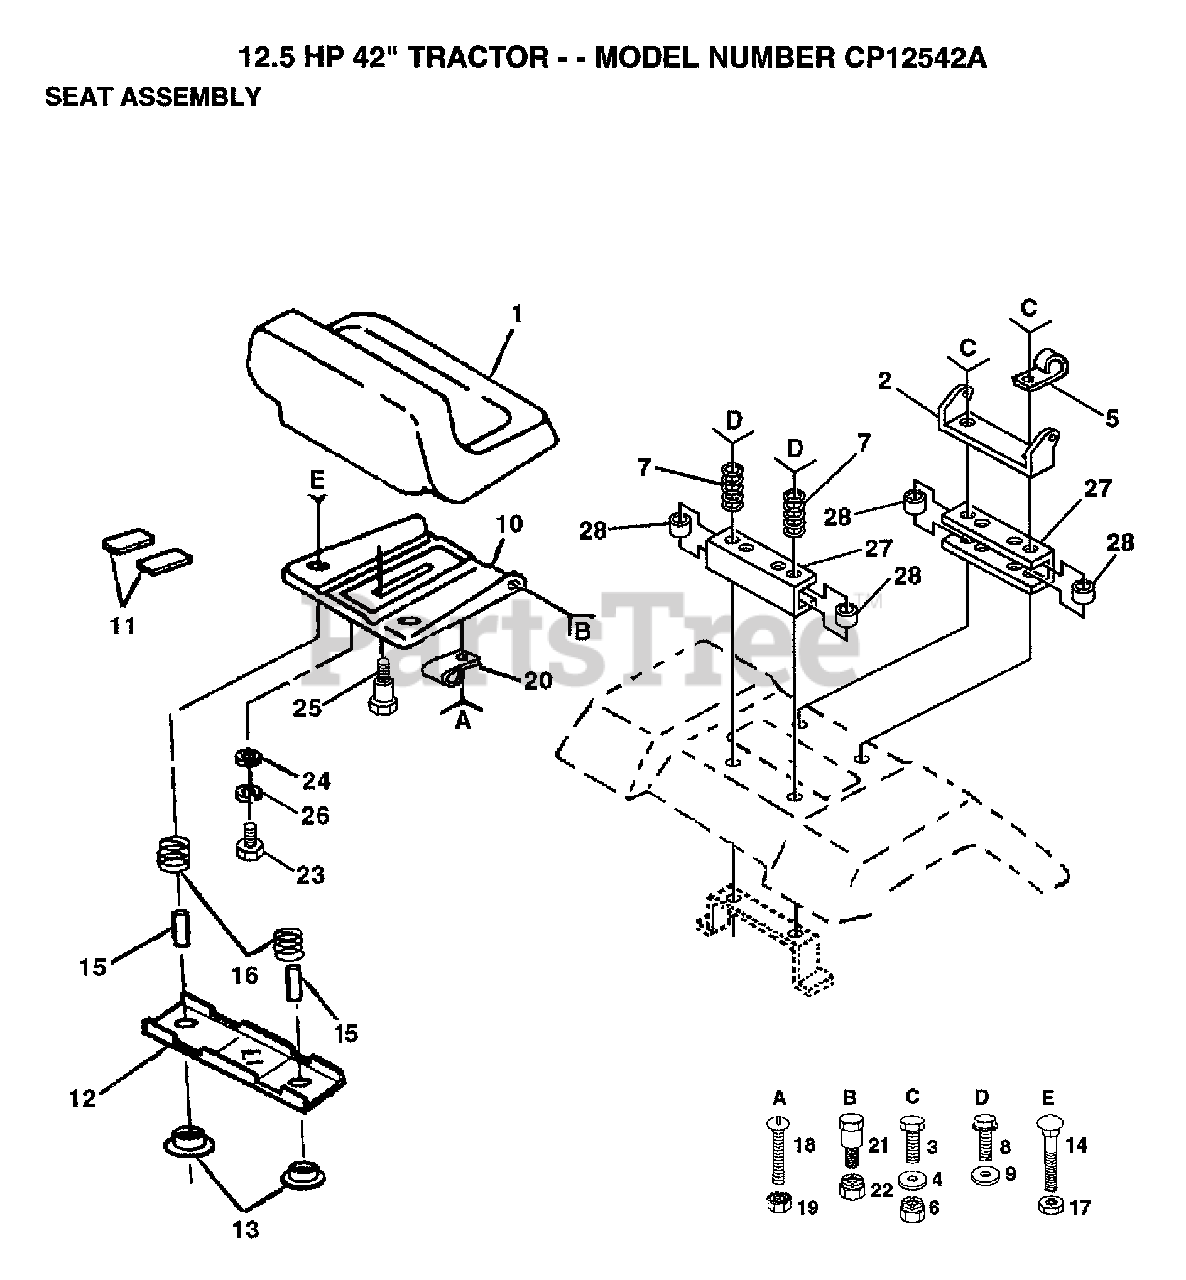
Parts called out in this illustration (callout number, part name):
3	BOLT
4	WASHER
5	CLIP T
7	SPRING COMPRESSIO
8	SCREW
9	WASHER
11	STRIP FORM
12	BRKT SWITCH
13	BUSHING
15	SPACER SPLIT
16	SPRING
19	"NUT,KEPS"
23	BOLT
24	WASHER
25	"BOLT,SHOULDER"
26	LOCKWASHER
27	SEAT SPACER
28	SPLIT SPACER
